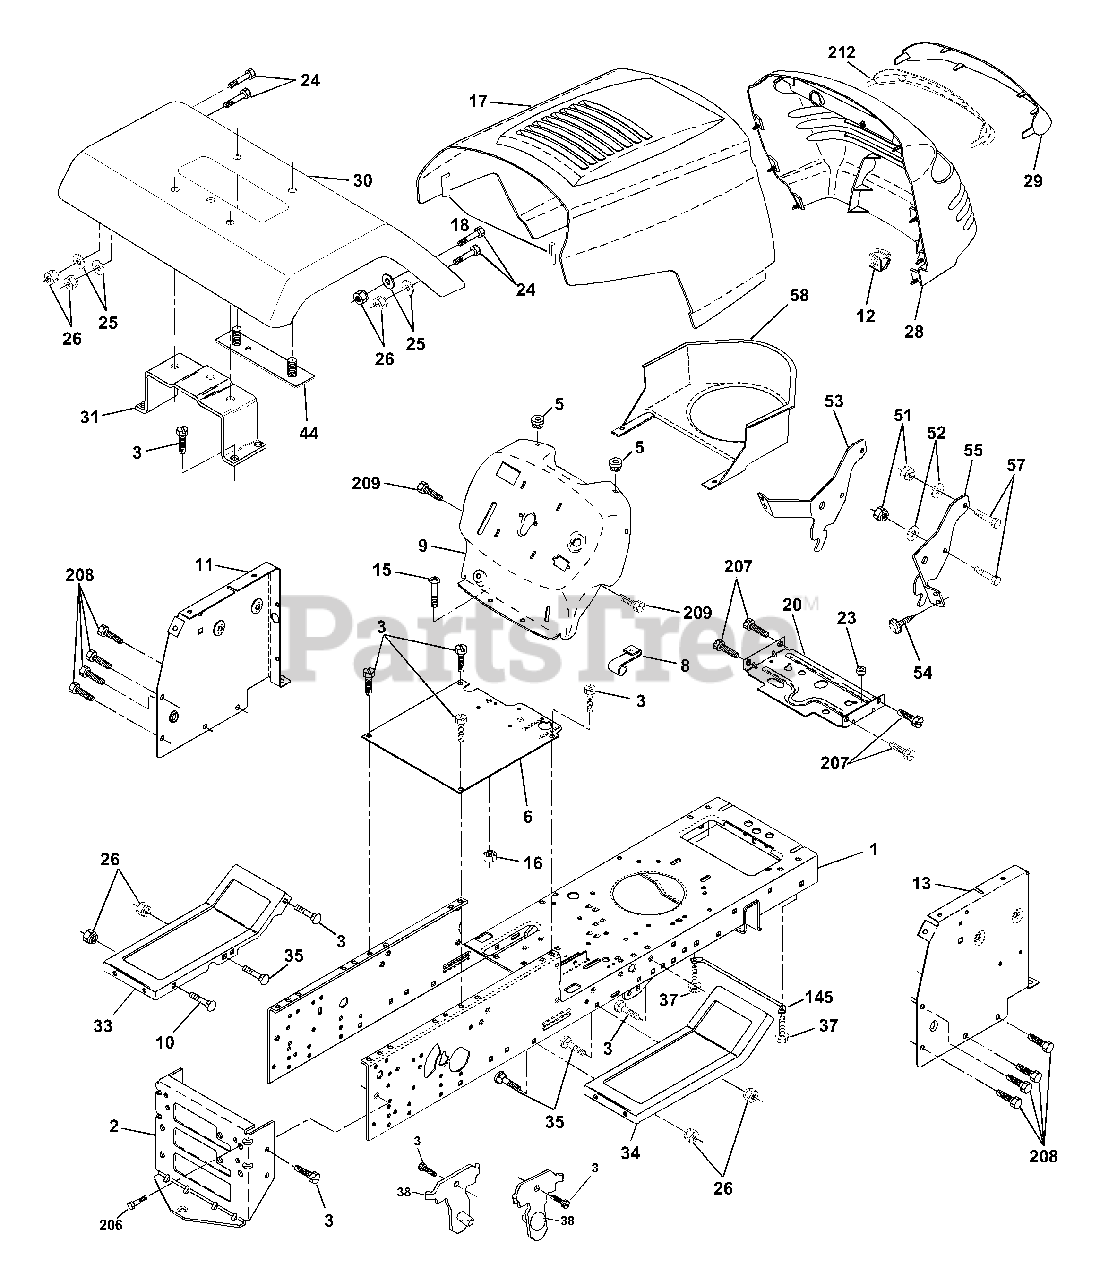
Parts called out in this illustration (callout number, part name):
2	Drawbar
3	Screw 3/8-16 x 3/4
5	Bumper Hood/Dash
6	Saddle
8	Clip
9	Dash
10	Bolt Rd Hd Sqnk. 3/8-16 x 1
11	Panel Dash Lh
12	Clip Tinnerman Grille P/L
13	Panel Dash Rh Slkscr
15	Screw Mach Trhd 5/16-18 UNC x 3/4
16	Nut Keps 5/16-18 UNC
17	Hood Pnt Steel Private Label
18	Bumper Hood
20	Plate Mtg Battery/Fuel Tank
23	Bushing Snap Nyl. Blk Fuel Line
24	Bolt Fin Hex 3/8-16 Unc x 1 Gr. 5
25	Washer 13/32 x 13/16 x 12 Ga.
26	Nut Lock Hex w/Ins 3/8-16 Unc
28	Grill
29	Lens
31	Bracket Fender Support
33	Footrest Pnt. Lh
34	Footrest Pnt. Rh
35	Bolt Rd Hd Sht. Sqnk. 3/8-16 x 3/4
37	Screw Thdrol 5/16-18 x 1/2
38	Bracket Asm. Pvt. Mwr. Rear
44	Strap Asm Pnt Fender
45	Rod Pivot Chassis/Hood
51	Nut Lock Hex W/Ins. 1/4-20
52	Washer 9/32 x 7/8 x 16 Ga.
53	Bracket Grille LH
54	Screw Hex Wshd 8-18 x 7/8
55	Bracket, Grille RH
57	Bolt Fin Hex 1/4-20 x 3/4
58	Air Duct Engine
206	Bolt Shoulder 5/16-18
207	Screw Thdrol 5/16-18 x 1/2
208	Screw Thdrol 3/8-16 x 1/2
209	Screw Hex Wsh Thdrol 3/8-16 x 3/4
212	Insert Lens
